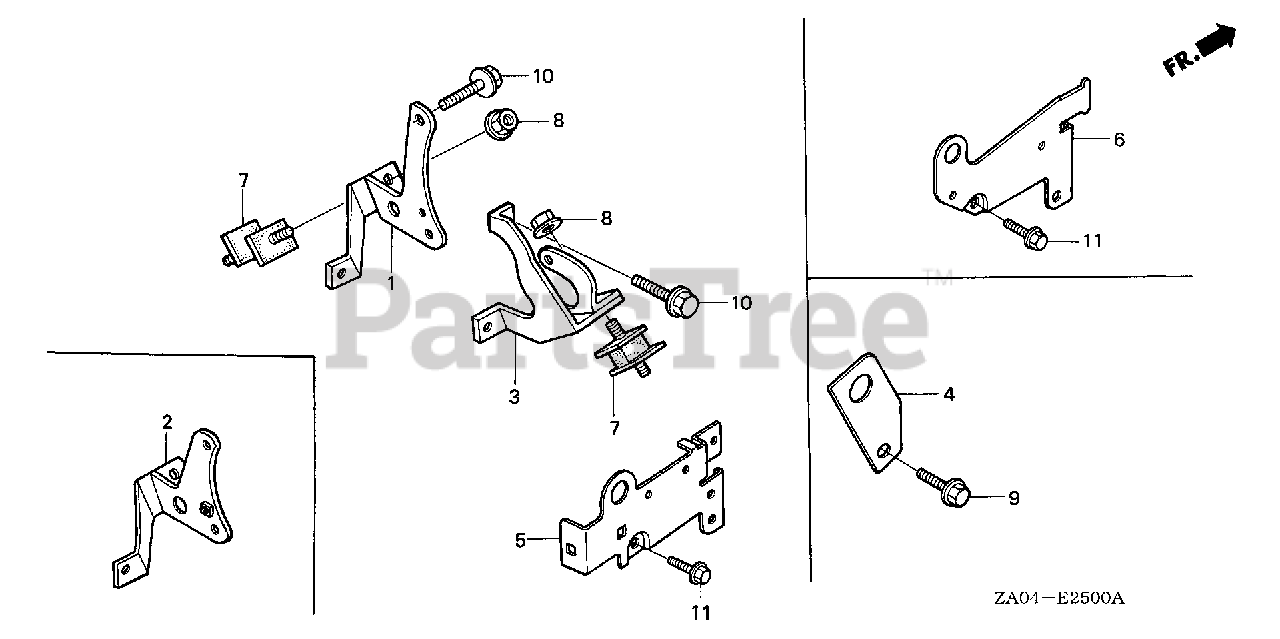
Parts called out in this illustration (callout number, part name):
2	STAY, ENGINE MOUNTING
3	STAY, L. ENGINE MOUNTING
6	STAY, IGNITION CONTROL MODULE (CDI)
7	RUBBER, ENGINE MOUNTING
8	NUT, FLANGE (10MM)
10	BOLT, FLANGE (8X20)
11	BOLT, FLANGE (8X12)
